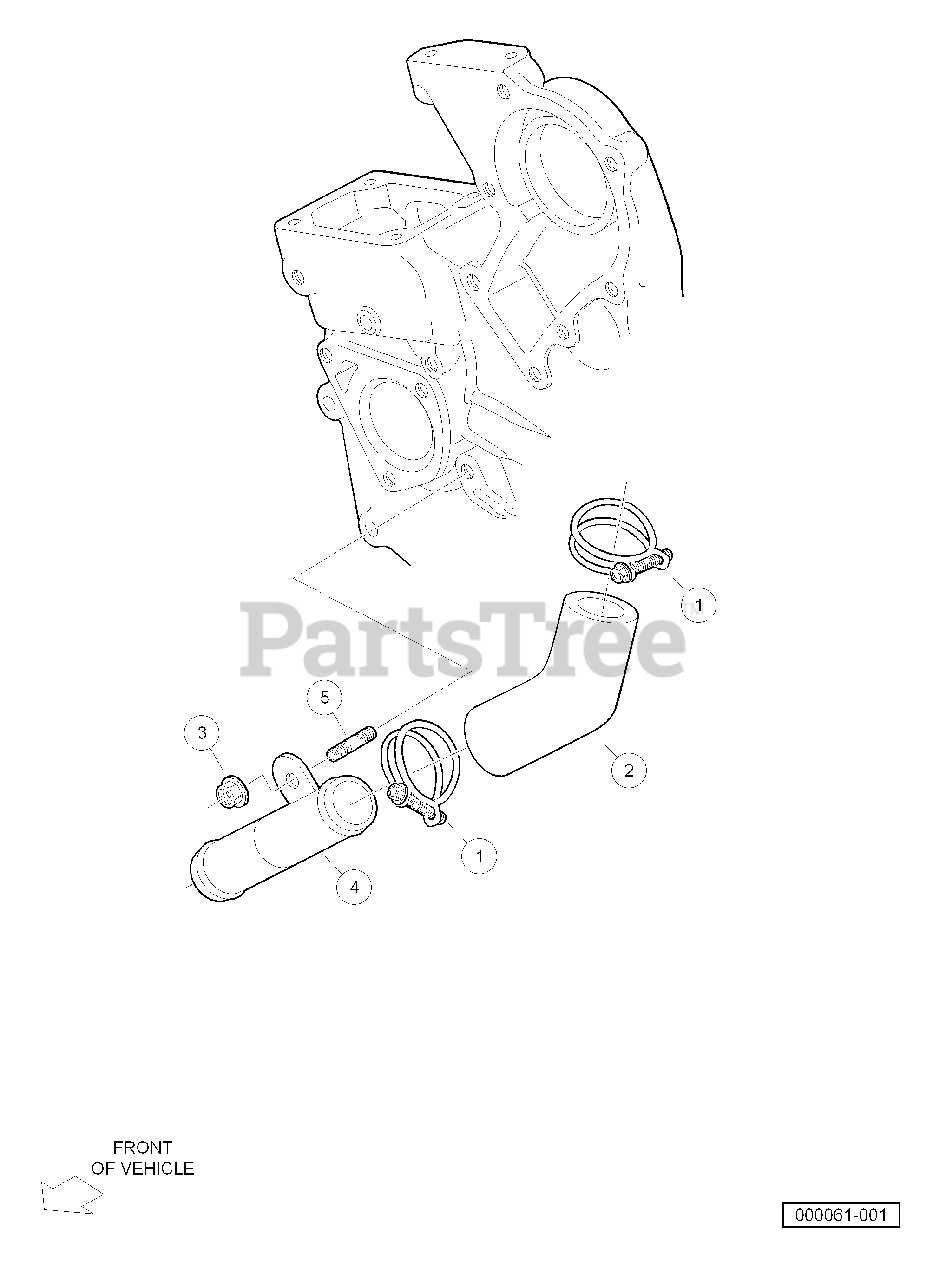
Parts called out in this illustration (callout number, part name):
1	Band, Pipe, with Nut
2	Pipe, Water, Bent
3	Nut, Flange, M6
4	Pipe, Water, Bent
5	Stud, M6 X 15
